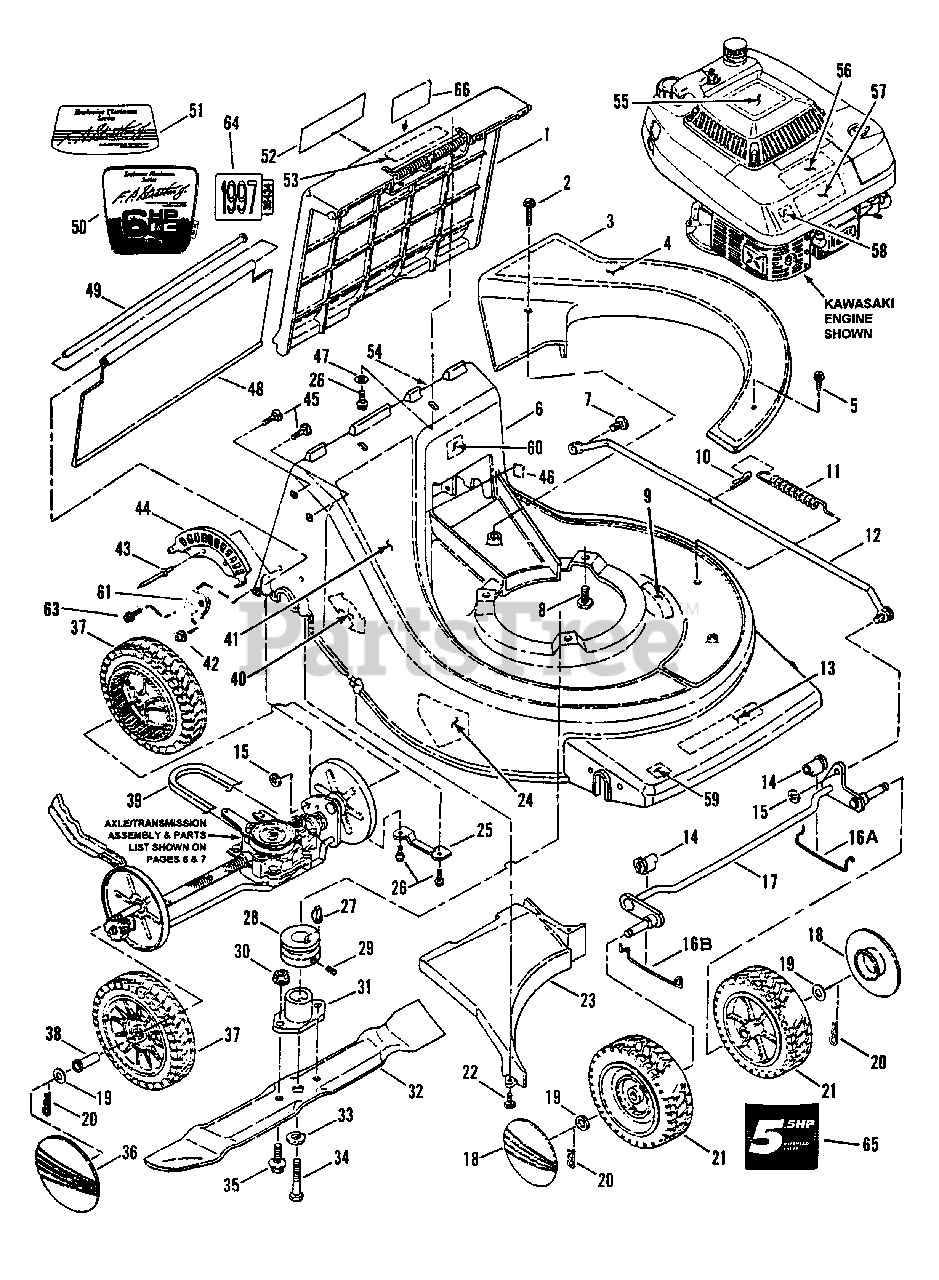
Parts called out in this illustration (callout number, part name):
1	ASSEMBLY, Discharge Door
2	SCREW, #10-24 x 1 1/2" Slotted, Hex Washer Head, Self-Tapping
3	COVER, Belt/Tie Bar
4	DECAL, Cover
5	SCREW, #10-24 x 1" Slotted, Hex Washer Head, Self-Tapping
6	DECK, 21" Cast Aluminum
7	PIN, Tie Bar, 3/8 x 5/8"
8	SCREW, 3/8-16 x 1 Hex Head, Self-Tapping
9	DECAL - WARNING (Deck)
10	COTTER-PIN, 1/8 x 3/4
11	SPRING, Tie Bar
12	ASSEMBLY, Tie Bar
13	LOGO, SNAPPER Platinum Series
14	BUSHING, Front Axle
15	RETAINER, Wheel
16A	SPRING, Axle Retaining (Left Side)
16B	SPRING, Axle Retaining (Right Side)
17	ASSEMBLY, Front Axle
18	HUB-CAP, Front Wheels
19	WASHER, 1/2 Flat
20	HAIRPIN, .062 x .900
21	ASSEMBLY, Wheels (Front)
22	SCREW, #10-24 x 5/8 Slotted, Hex Washer Head, Self-Tapping
23	BAFFLE, Discharge
24	DECAL - DANGER
25	SUPPORT, Rear Axle
26	SCREW, 1/4-20 x 5/8 Hex Washer Head, Self-Tapping
27	KEY, HP-506 Hi-Pro
28	PULLEY, Traction Drive
29	SCREW, 5/16-18 x 5/16" Hex. Socket Set
30	NUT, 3/8-16 Hex Nyloc
31	HUB, 25 mm Blade Drive
32	BLADE, 21 Bagging
33	WASHER, 3/8 Split Lock (Heavy)
34	SCREW, 3/8-24 x 1 3/4" Hex Head Cap, Grade 5
35	BOLT, 3/8-16 x 1 1/4" Hex Flange Lock
36	HUB-CAP, Rear Wheels
37	ASSEMBLY, Rear Drive Wheels
38	BUSHING, Rear Wheel
39	BELT, Traction Drive
40	DECAL, Height Adjustment
41	DECAL, Deck (Right Side)
42	PUSH-NUT, 1/4"
43	RIVET, 3/16 x 1/2" Steel
44	PLATE, Height Adjustment
45	BOLT, 5/16-18 x 1 Carriage, Gr. 5
46	DECAL, Patent Numbers
47	WASHER, 1/4 Flat
48	SHIELD, Trailing
49	ROD, Trailing Shield Pivot
50	DECAL, Briggs & Stratton, 5.5HP Diamond-Plus I/C
51	DECAL, Exclusive Platinum Series
52	DECAL, Convertible Mower
53	DECAL, - WARNING
54	DECAL, Deck/Chute, International Warning
55	DECAL, Kawasaki Engine (Starter)
56	DECAL, Kawasaki Engine (OHV)
57	DECAL, Kawasaki Engine 5HP (OHV)
58	DECAL, Spark Plug
59	DECAL, European Community
60	DECAL, Noise Control
61	BRACKET, RH TS Pivot Rod
63	SCREW, 1/4-20 x 5/8" Hex Washer Head Self-Tapping
64	DECAL, 1997 Year of Manufacture
65	DECAL, 5HP Overhead Valve
66	DECAL, Warning
